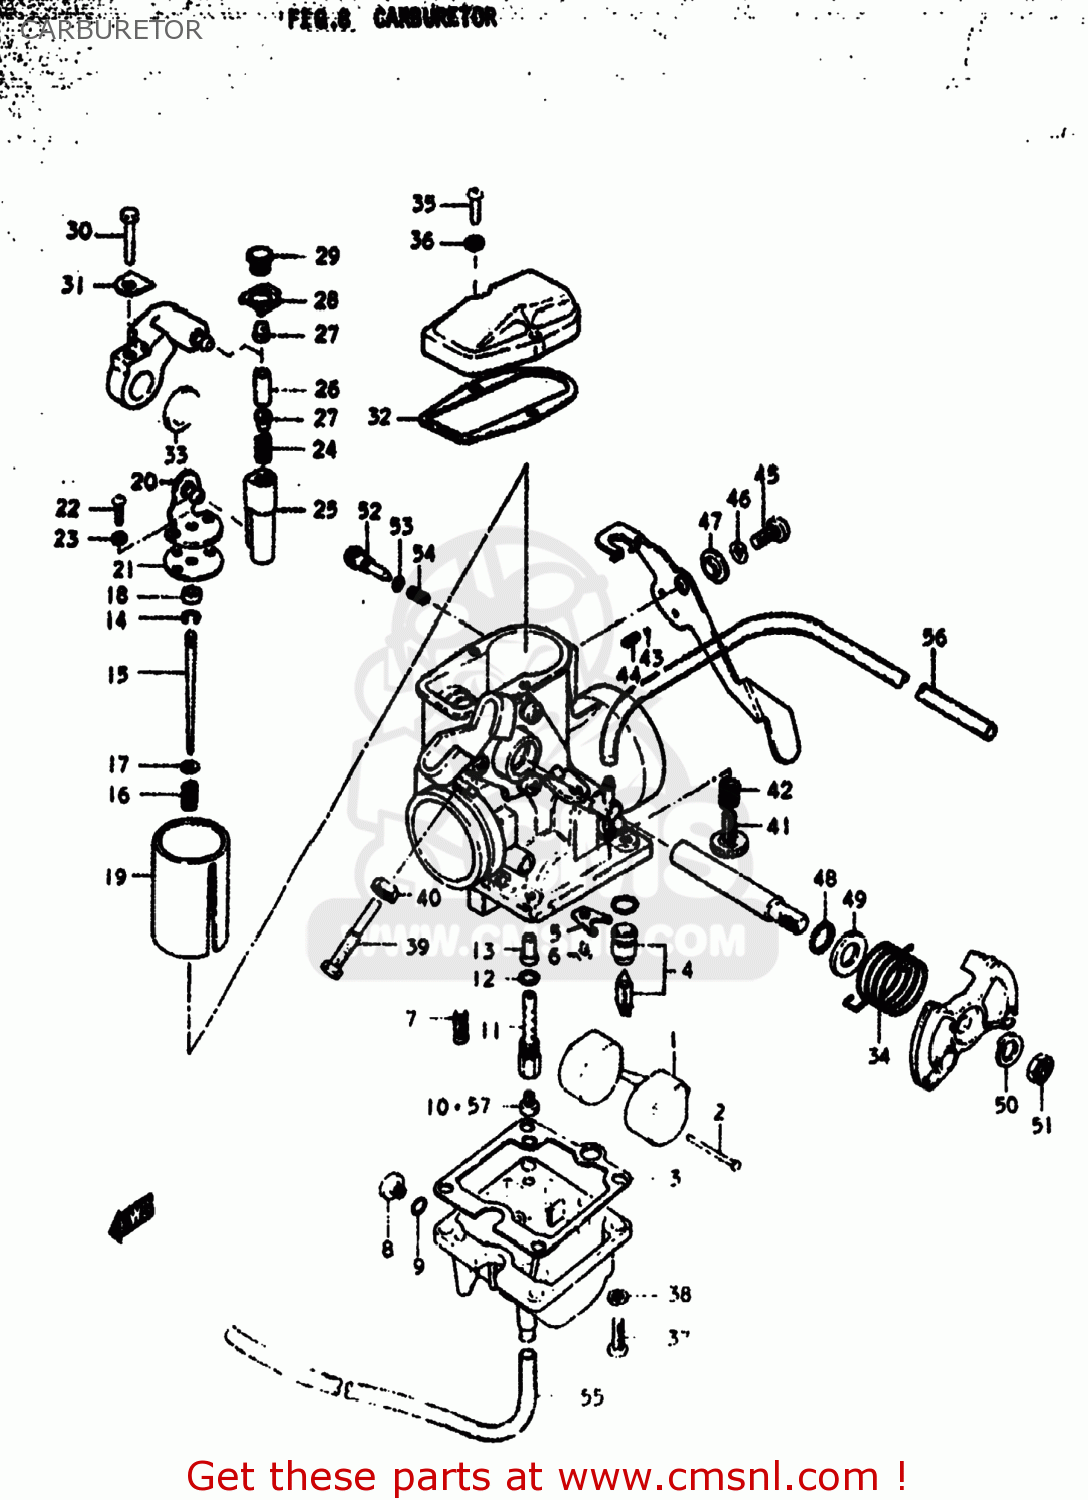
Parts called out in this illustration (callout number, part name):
1	FLOAT
2	PIN,FLOAT
3	GASKET,FLOAT CAHMBER (NAS)
4	VALVE ASSY,NEEDLE
5	PLATE
6	SCREW
7	JET
8	SCREW
9	O RING
10	JET
11	HOLDER,JET
12	O RING
13	JET,NEEDLE
14	CLIP
15	NEEDLE JET
16	SPRING
17	WASHER,JET NEEDLE
18	RING
19	VALVE,THROTTLE
20	BRACKET,CARBURETOR
21	PLATE,THROTTLE VALVE
22	SCREW
23	LOCK WASHER
24	SPRING,CARBURETOR
25	LEVER ASSEMBLY
26	SPRING
27	PIN,CARBURETOR
28	PLATE,CARBURETOR
29	SCREW
30	BOLT
31	RING
32	GASKET,TOP (NAS)
33	RING
34	SPRING,THROTTLE VALVE
35	SCREW
36	LOCK WASHER
37	SCREW
38	LOCK WASHER
39	SCREW
40	NUT
41	ADJUSTER
42	SPRING,THROTTLE SCREW
43	BALL,CARBURETOR
44	SPRING
45	SCREW 6X12
46	LOCK WASHER
47	RING,CARBURETOR STARTER
48	SEAL
49	RING
50	WASHER
51	NUT
52	SCREW,PILOT AIR ADJUSTING
53	O RING
54	SPRING
55	HOSE
56	HOSE
57	JET
